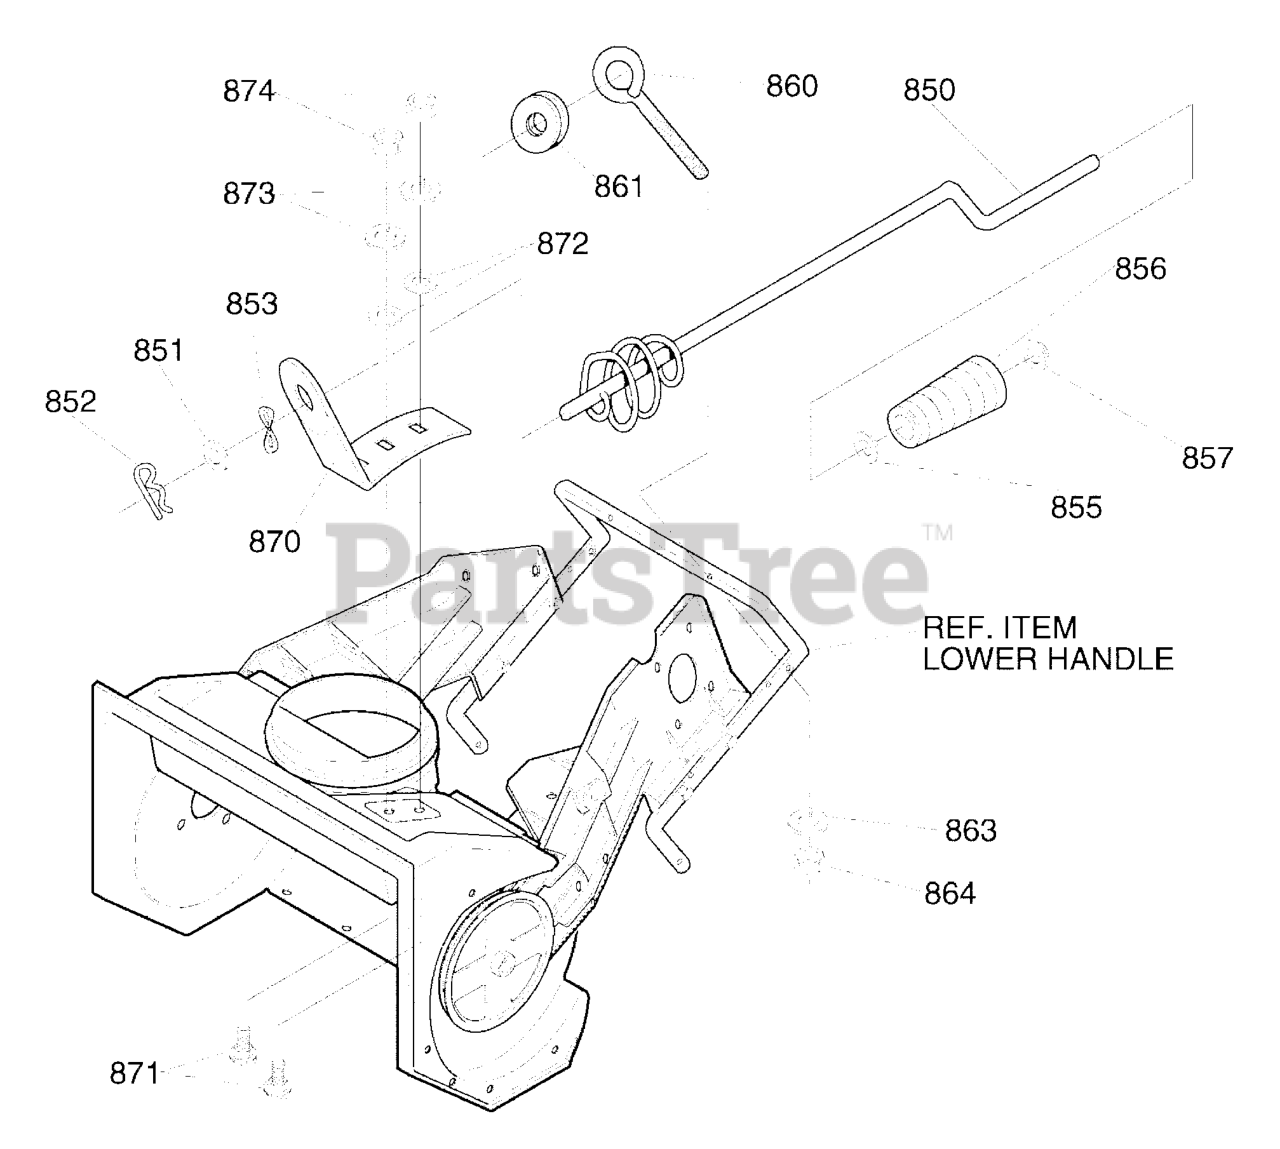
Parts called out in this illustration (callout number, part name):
850	ROD, ASSY UPPER CHUTE CONTROL
851	WASHER, FLAT .406X.81X.066
852	PIN, COTTER
853	WASHER, CURVED SPRING
855	WASHER, FLAT .406X.81X.066
856	KNOB, SLEEVE
857	NUT, PUSH
860	BOLT, EYE 3/8-16X2.00
861	GROMMET, EYE BOLT
863	WASHER
864	NUT, HEX JAM 3/8-16
870	BRACKET, CHUTE ROTATE
871	BOLT, CARRIAGE 5/16-18X.75
872	WASHER, FLAT .349X.69X.066
873	WASHER .328X.60X.09
874	NUT, HEX 5/16-18
